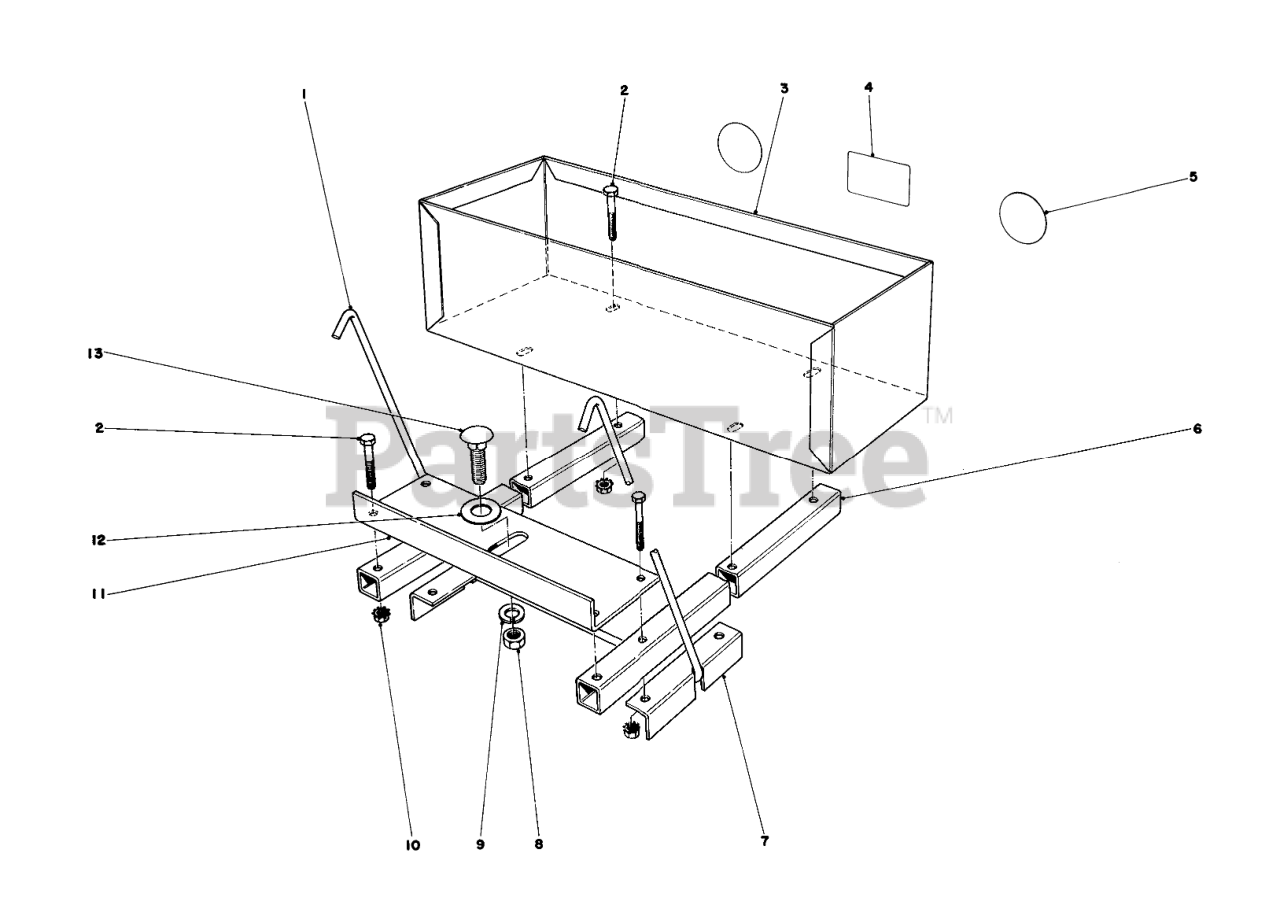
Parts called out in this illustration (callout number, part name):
1	Bracket-Support
2	SCREW-HH
3	Weight Box
4	Decal-Weight Box
5	Reflector
6	Tube-Mounting
7	Bracket-Mounting
8	NUT-HEX
9	WASHER-LOCK
10	NUT-KEPS
11	Bracket-Mounting
12	Washer
13	SCREW-CARR
